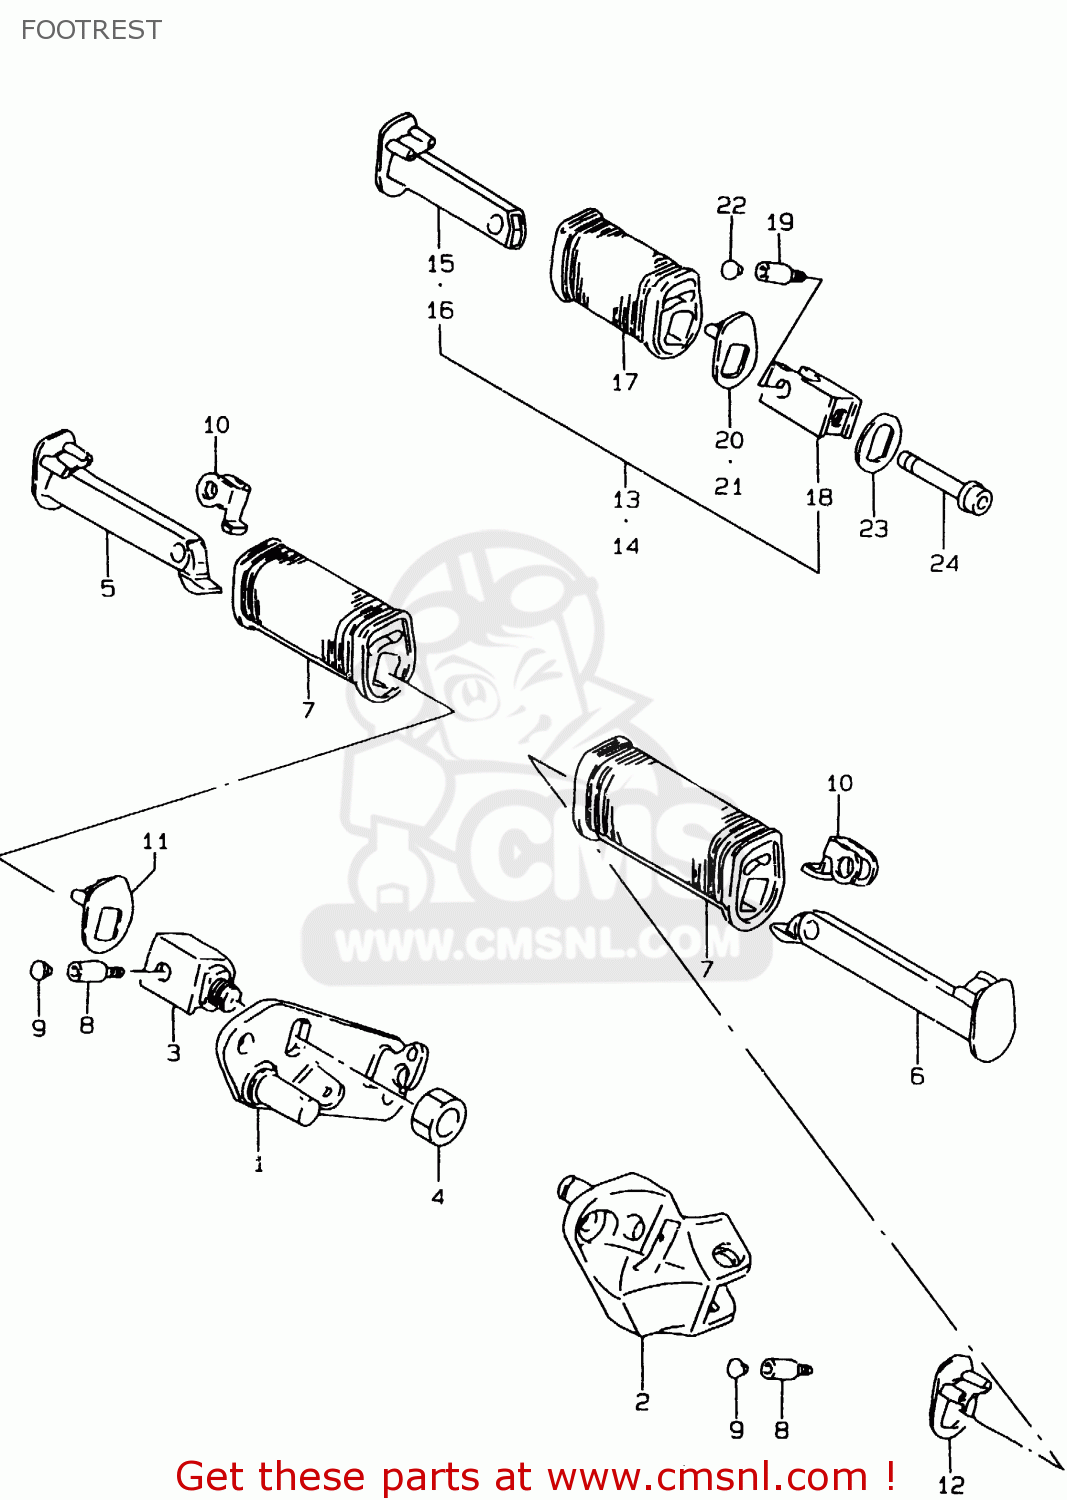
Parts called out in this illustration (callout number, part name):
1	BRACKET,FR FOOTREST,R
2	BRACKET,FR FOOTREST,L
3	HOLDER,FR FOOTREST,R
4	NUT
5	BAR,FR FOOTREST,R
6	BAR,FR FOOTREST,L
7	RUBBER,FR FOOTREST
8	BOLT,FRONT FOOTREST RUBBER
9	CAP,PILLION FOOTREST BOLT
10	CUSHION,FR FOOTREST
11	WASHER,FR FOOTREST,R
12	WASHER,FR FOOTREST,L
13	FOOTREST ASSY,PILLION,R
14	FOOTREST ASSY,PILLION,L
15	BAR,PILLION FOOTREST,R
16	BAR,PILLION FOOTREST,L
17	RUBBER,PILLION FOOTREST
18	HOLDER,PILLION FOOTREST
19	BOLT,FRONT FOOTREST RUBBER
20	WASHER,FR FOOTREST,R
21	WASHER,FR FOOTREST,L
22	CAP,PILLION FOOTREST BOLT
23	WASHER,PILLION FOOTREST HOLDER
24	BOLT
